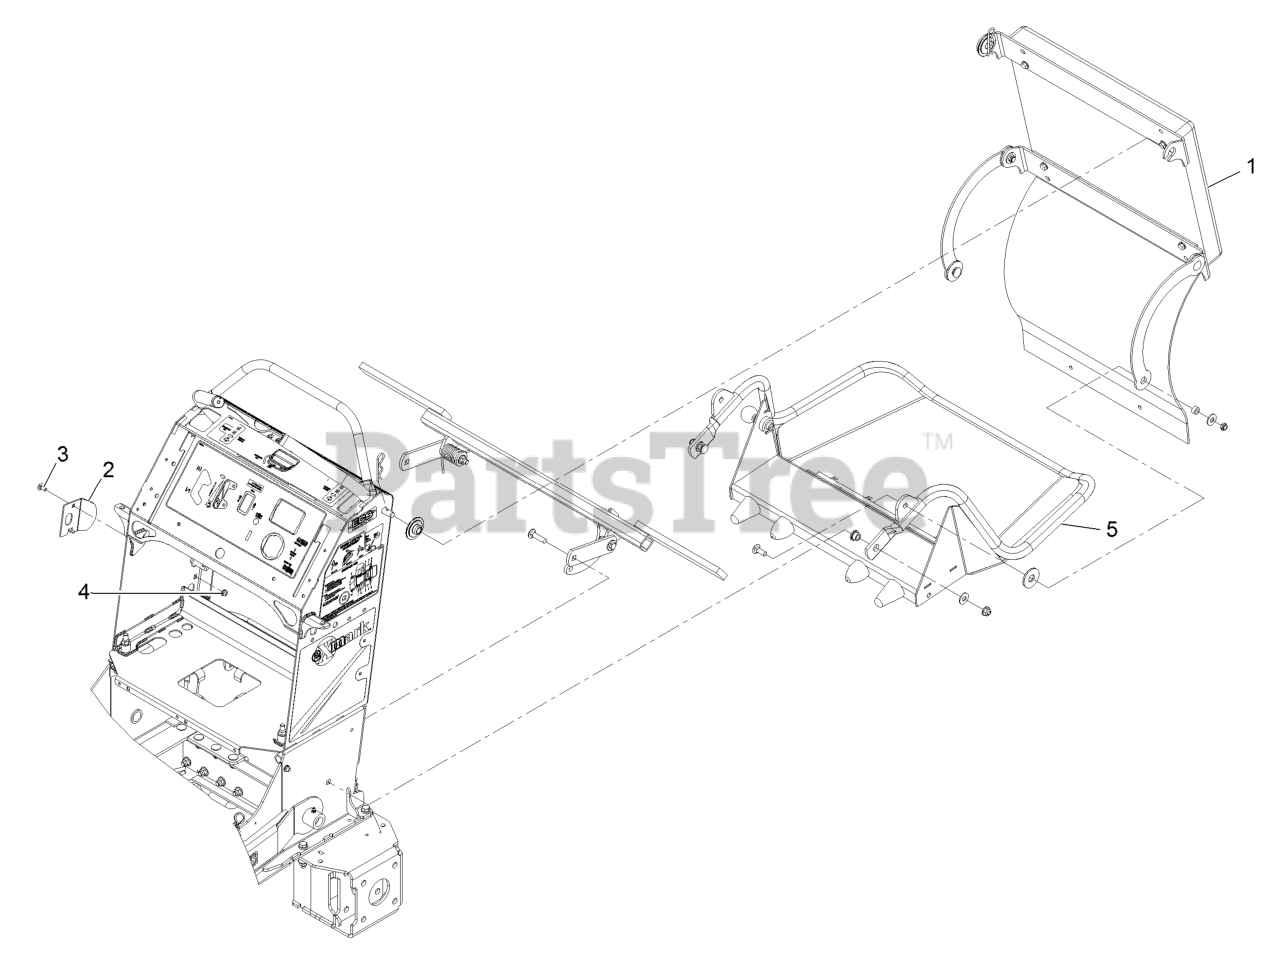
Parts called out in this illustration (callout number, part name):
2	PLATE-STRIKER
3	SCREW-CARR
5	ASM,PLATFORM
